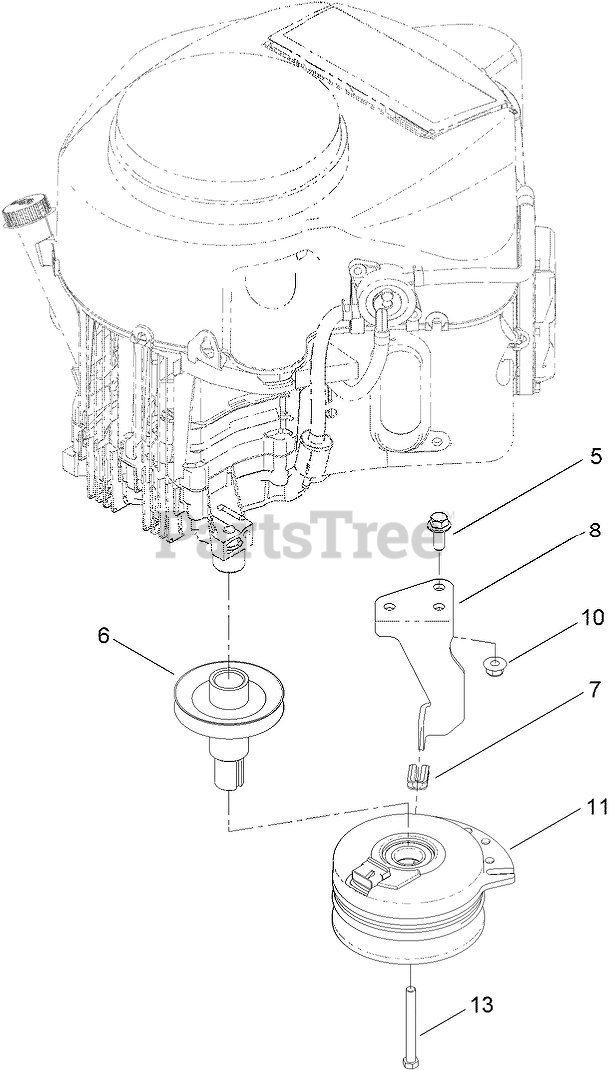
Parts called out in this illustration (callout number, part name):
5	SCREW-HHF
6	PULLEY-ENGINE
7	ISOLATOR-CLUTCH
8	STOP-CLUTCH (NARROW)
10	NUT-HF, NI
11	CLUTCH-ELECTRIC
13	SCREW-HH
